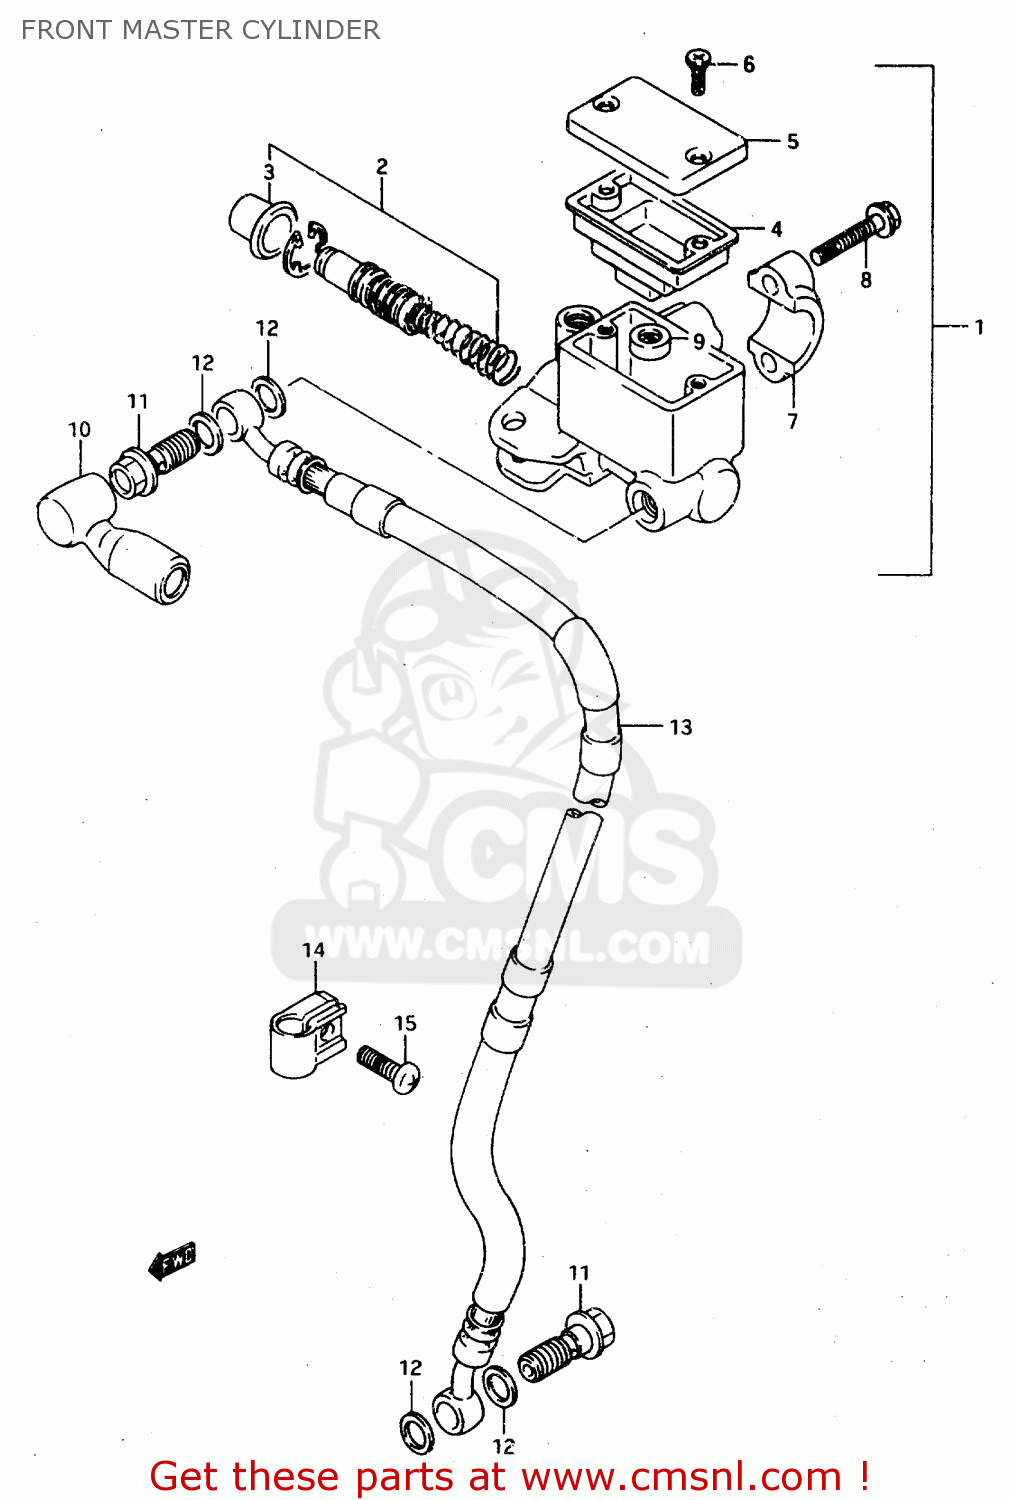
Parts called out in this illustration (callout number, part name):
1	CYLINDER ASSEMBLY,FRONT MASTER
2	PISTON/CUP SET
3	BOOT
4	DIAPHRAGM
5	CAP
6	SCREW 4X12
7	HOLDER
8	BOLT
9	SEPARATOR
10	BOOT,MASTER CYLINDER
11	BOLT UNION
12	WASHER(10X15X1.5)
13	HOSE, FRONT BRAKE (L:1385)
14	CLAMP,BRAKE HOSE
15	SCREW
